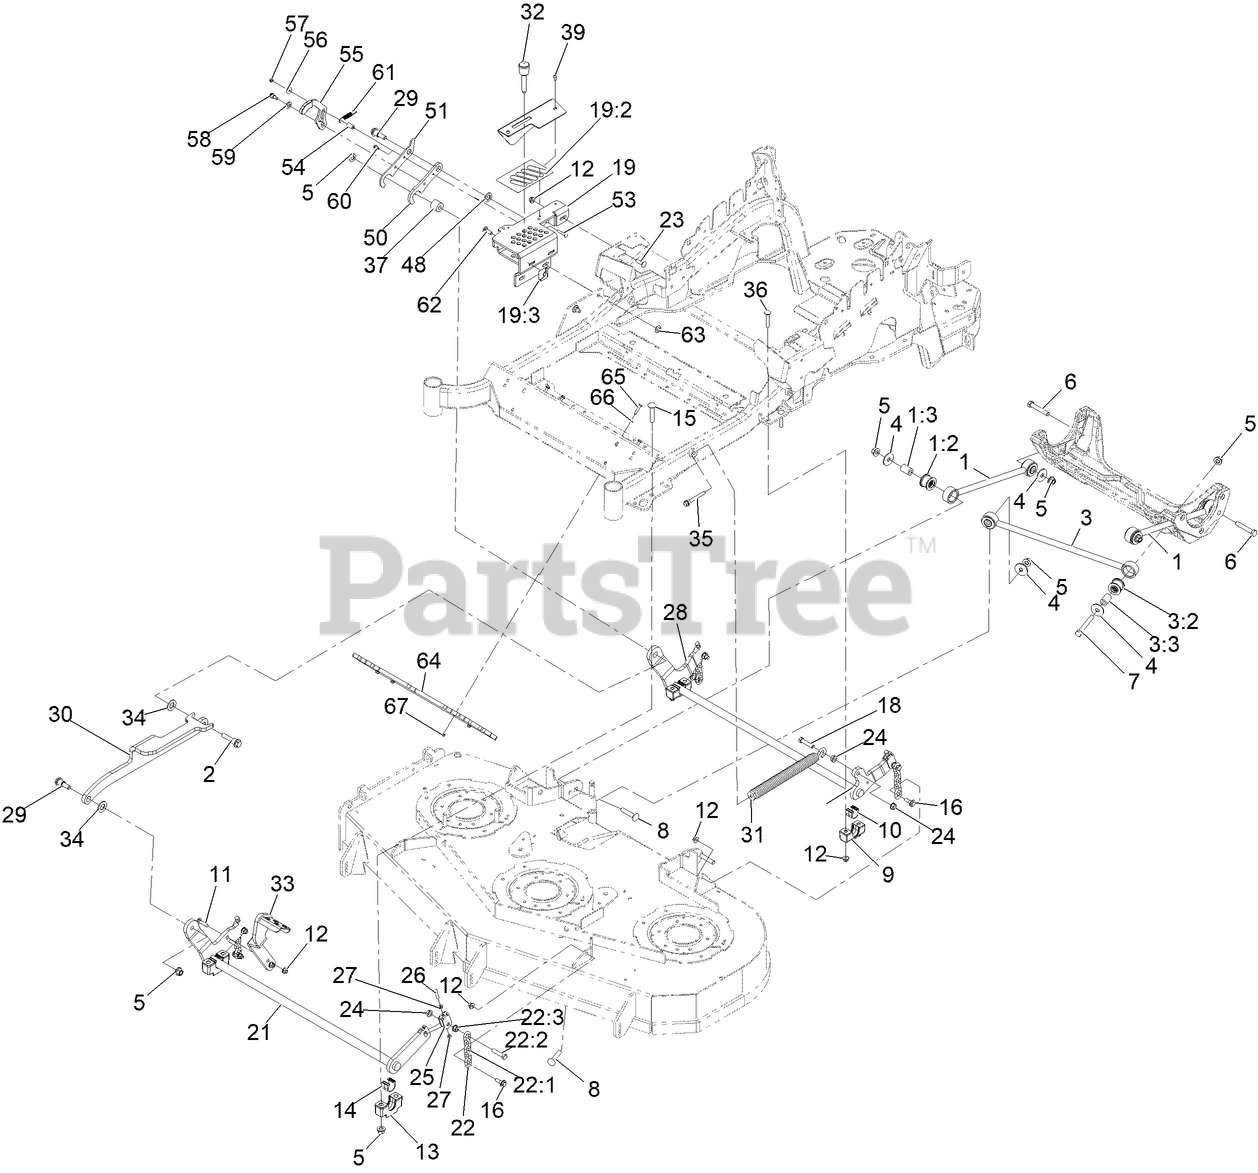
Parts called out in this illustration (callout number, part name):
1	DECK STRUT ASM
1:2	BUSHING-SUSPENSION, RUBBER
2	SCREW-HHF, SHOULDER
3	PANHARD ROD ASM
3:2	BUSHING-SUSPENSION, RUBBER
4	WASHER-THRUST
5	Nut-Lock 1/2-13
6	SCREW-HH
7	SCREW-HH
8	SCREW-CARR
9	SUPPORT-CROSS SHAFT, BEARING REAR
10	BEARING-CROSS SHAFT, REAR
11	SCREW-CARR
12	NUT-HF, NI
13	SUPPORT-CROSS SHAFT, BEARING
14	BEARING-CROSS SHAFT, FRON
15	Bolt-Carriage 1/2-13 X 2 1/2 Spl Neck
16	SCREW-SHOULDER, HHF
18	SCREW-HH
19	ASM-HOC Box W/ Decals
19:2	Decal-HOC
19:3	DECAL-PARK BRAKE, CE
21	Weld-Xshaft Front
22	DECK LIFT CHAIN ASM
22:1	CHAIN-LIFT, DECK
22:2	SCREW-HH
23	Bolt-Carriage 3/8-16 X 1 1/4
25	YOKE-ADJUST, DECK
26	SCREW-HH
27	NUT-JAM
28	Weld-Xshaft Rear
29	SCREW-SHOULDER, HHF 1/2-13 X 1.12
30	Link-Decklift
31	SPRING-EXTENSION
32	ASM- HOC PIN
33	LEVER-FOOT
34	WASHER-FLAT
35	BOLT-SHOULDER
36	Bolt-Carriage 3/8-16 X 2 1/4
37	Bushing- Link
39	SCREW-TPH THD FORM
50	Plate- Pawl
51	Plate- Pawl
53	SCREW-CARR
54	Spacer- 0.50" OD
55	Lever- Transport W/Grip
57	NUT-LOCK, NI
58	BOLT-SHOULDER
59	SPACER
60	SCREW-HWH
61	Spring- Extension
62	Bolt-Carriage 3/8-16 X 1 1/4
63	Nut-Nyloc 3/8-16 Flg
64	Weight-Toe Board
65	SCREW-HH
66	WASHER-FLAT
